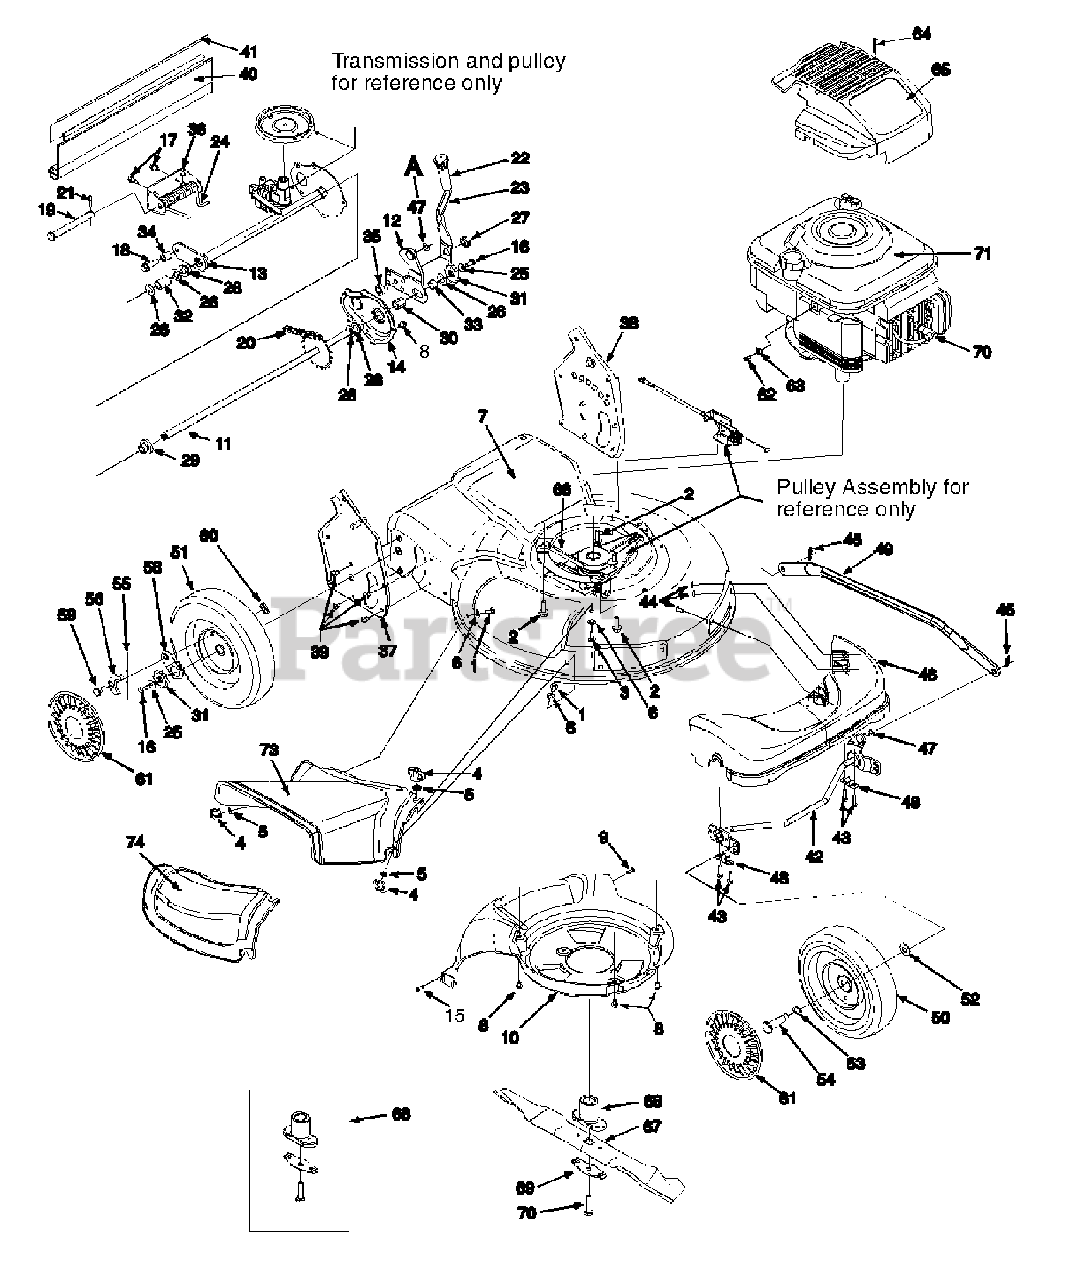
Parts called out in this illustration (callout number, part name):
1	Scr. Carr. 1/4-20 x .62
2	Scr. TT:3/8-18:1.00
3	Scr. 1/4-20 x .750
4	Wing Nut 1/4-20
5	Nut, Push .25 I.D. x .50 O.D.
6	Wash. Fl. .334 I.D. x .62 x .03
8	Scr. TT. 1/4-20 x .375
9	Scr. Hex . 5/15-18
10	Baffle
11	Rear Axle Ass'y
16	Cap Screw HH 1/4-20 x .620
17	Scr., AB 1/4-14 x .825
18	Scr., 3/8 116 x .25
19	Clevis Pin .50 Dia. x 4.82 Lg.
20	Chain-Endls. #48 .500P x 24L
21	Cotter Pin .125 O.D. x .75
24	Torsion Spring
25	Bell Wash. .285 x .75 x .082
26	Fl. Wash. .508 I.D. 1.000 x .020
27	Nut Shld. .825 Dia. x .165 Lg.
28	Hx . Flg. Brg. .506 I.D. x .590 L.
29	Hx . Flg. Brg. .506 I.D. x .715 L.
30	Hx . Slv. Brg. .504 I.D. x .830 L.
31	Wheel Rachet
32	Spa. .550 I.D. x /750 O.D.
33	Spa. .51 .D. x .70 O.D. x 38 L.
34	Spa. .385 x .624 x .700
35	Shld. Spa. .385 I.D. X .715 Lg.
38	Handle Brkt. Assembly L.H.
39	Scr. AB 1/4-14 x .500
40	Trail Shield
41	Trail Shield Wire
42	Fr. Axle Ass'y.
43	Hx Scr. Wash Hd. Hi.-Lo.
44	Scr. Torx, Truss Hi.-Lo.
45	Cotter Pin .072 x 1.12 Lg.
46	Fr. Axle Cover
47	Bowed Washer
48	Bush. Block .505 Dia. x .62
49	Control Arm
50	Wheel 8 x 2 Link Gray
51	Wheel 9 x 2 Link Gray, Sleeve
52	Spr. Wash. .401 x .870 x .063
53	Wave Wash .510 x .750 x .017
54	Shldr Scr .498 x 1.445 x 3/8-16
55	Spring, Ratchet, Plastic
56	Pawl - L.H.
58	Ratchet Pawl Plate
59	Hubcap - Gray
60	Top Lock Tab Weld Nut 1/4-20
61	Hubcap - Gray
62	Screw .620 Hx . Slt. Wsh.
63	Casing Clamp, Throttle
64	Scr. Hi-Lo #10 x 1.25
65	Shroud - Gray
66	Belt
67	21" Mulching Blade
68	Blade Adapter Kit
69	Blade Bell Support
70	Hex Bolt 3/8-24 x 2.5" Lg.
71	Engine
72	Spark Plug Insulator
73	Side Discharge Chute
74	Mulch Cover
